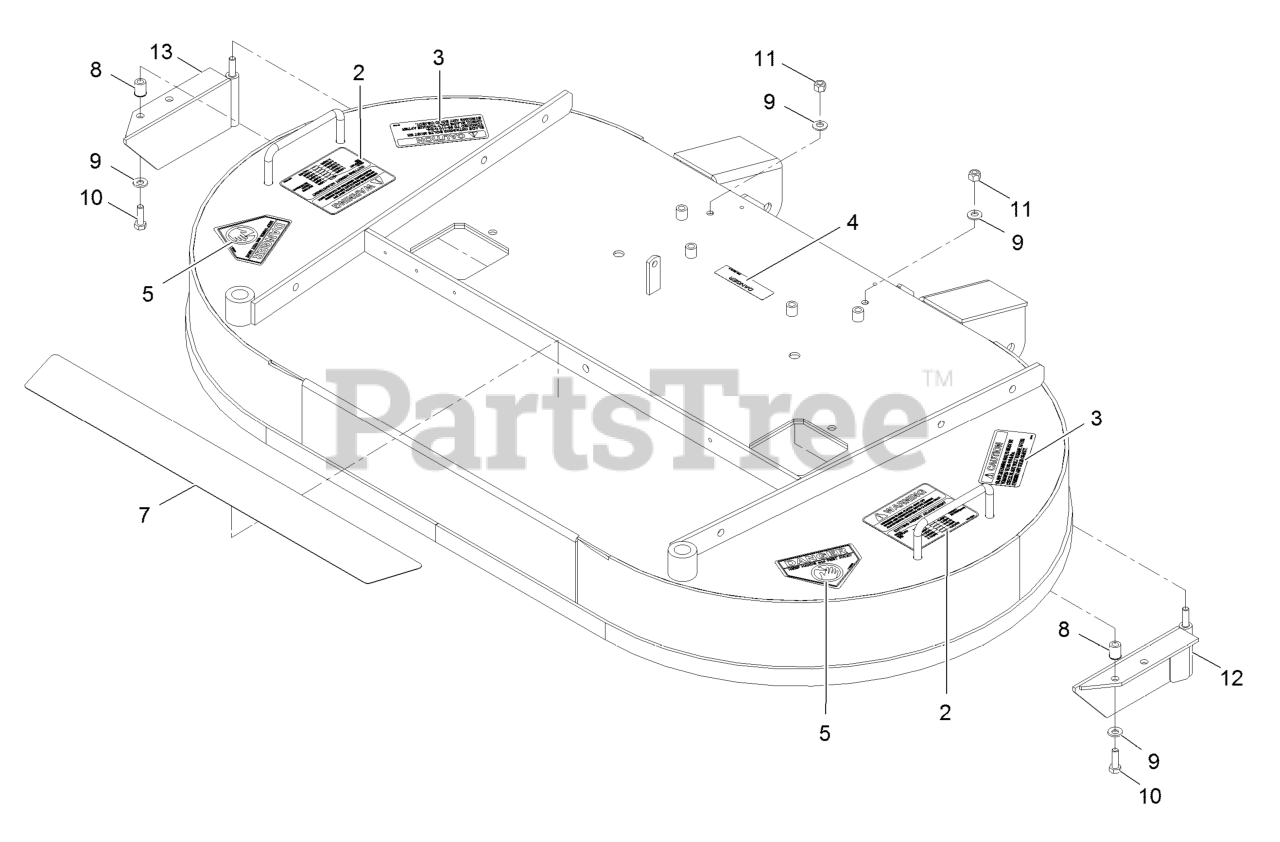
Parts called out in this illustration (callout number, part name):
3	DECAL-TORQUE
4	DECAL-COVER, MISSING
5	DECAL-DANGER
7	PAD-ANTI SKID
8	NUT-CLINCH
9	WASHER-SPRING
10	SCREW-HH
11	NUT-LOCK, NI
12	BAFFLE-LH
13	BAFFLE-RH
